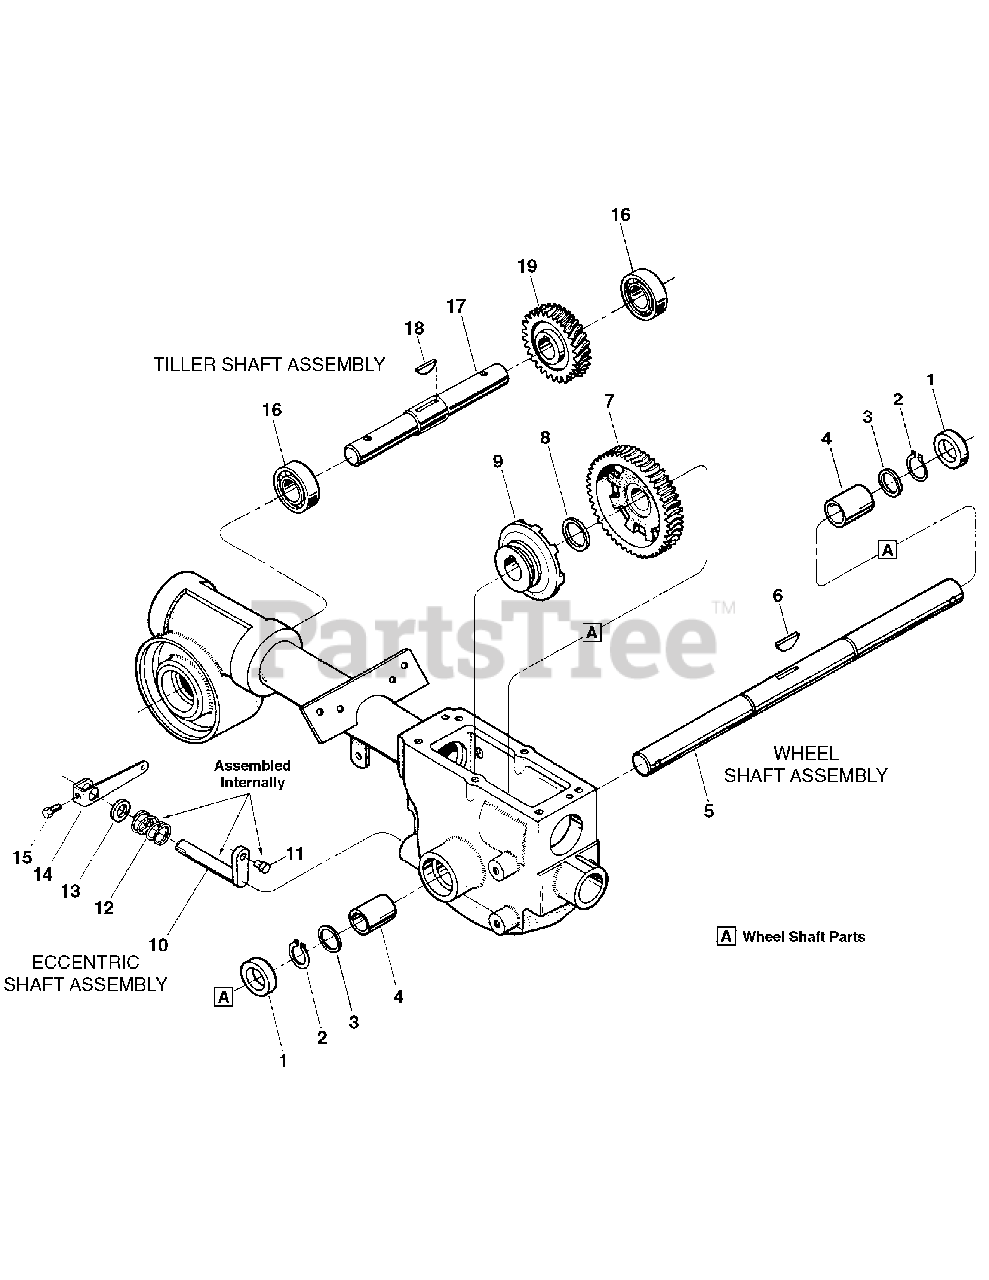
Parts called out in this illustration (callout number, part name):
1	Oil Seal
2	Retaining Ring (heavy duty external)
3	Shim, 1-1/64 I.D., .062" thick
3	Shim, as above, but .030 thick
3	Shim, as above, but .015 thick
3	Shim, as above, but .010 thick
4	Bushing
5	Wheel Shaft
6	Hi-Pro Key, 1/4 x 1-5/16
7	Wheel Drive Worm (cast iron)
8	Shim (between key and gear), 1.016 I.D. x 1.468 O.D. x .062 thick
9	Wheel Drive Clutch (cast-iron)
10	Eccentric Shaft
11	Pin, Eccentric Shaft
13	Oil Seal
14	Eccentric Shaft Lever
15	Hex Hd Screw 1/4-20 x 1/2 (specify grade 5 if ordering part locally)
16	Ball Bearing
17	Tiller Shaft
18	Woodruff Key, 1/4 x 1-1/4
19	Tiller Drive Worm Gear (bronze)
